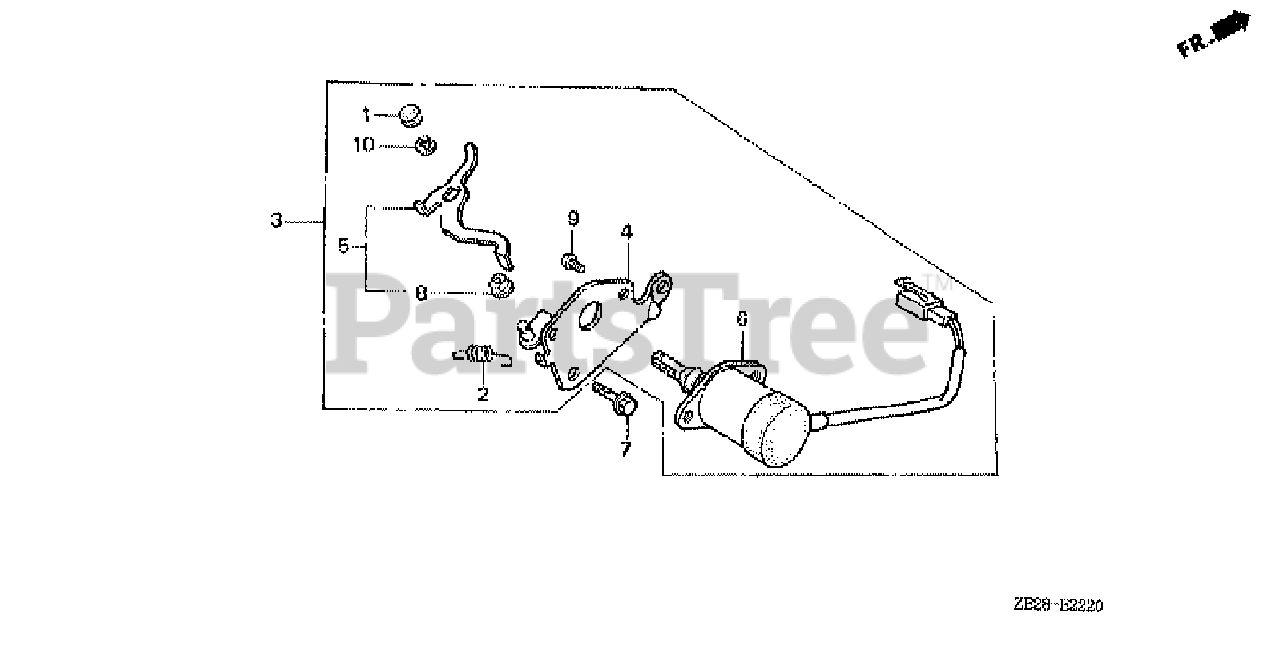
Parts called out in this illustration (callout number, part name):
1	CAP, CHOKE LEVER
2	SPRING, CHOKE RETURN
3	THROTTLE ASSY., AUTO
4	STAY, SOLENOID THROTTLE
5	LEVER, SOLENOID THROTTLE
6	SOLENOID ASSY.
7	BOLT, FLANGE (6X12) (CT200)
8	BUSH, AUTO-THROTTLE LEVER
9	SCREW, PAN (5X8)
10	E-RING (4MM)
